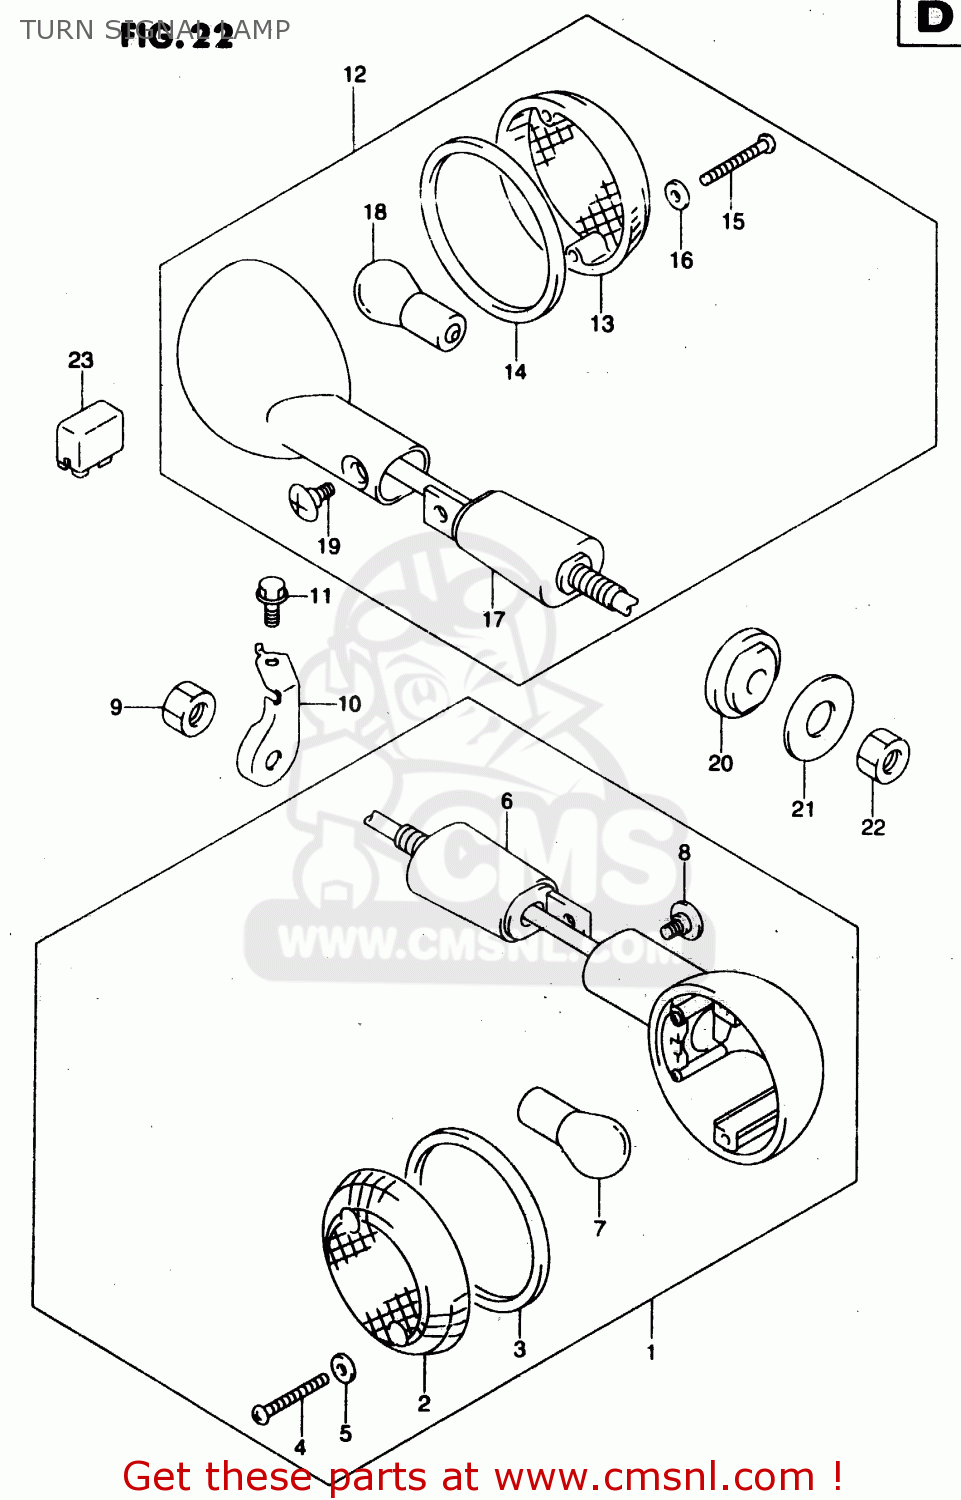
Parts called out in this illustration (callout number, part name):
1	LAMP ASSY,FR TURN SIGNAL
2	LENS
3	GASKET (NAS)
4	SCREW
5	GASKET (NAS)
6	STAY,TURNSIGNAL FR
7	BULB(12V21W)
8	SCREW
9	NUT
10	BRACKET,FR TURNSIGNAL,R
11	BOLT
12	LAMP ASSY,RR TURNSIGNAL
13	LENS
14	GASKET (NAS)
15	SCREW
16	GASKET (NAS)
17	STAY,TURNSIGNAL RR
18	BULB(12V21W)
19	SCREW
20	SPACER,RR TURNSIGNAL
21	WASHER(10.5X30X2.3)
22	NUT
23	RELAY ASSY,TURNSIGNAL LAMP
